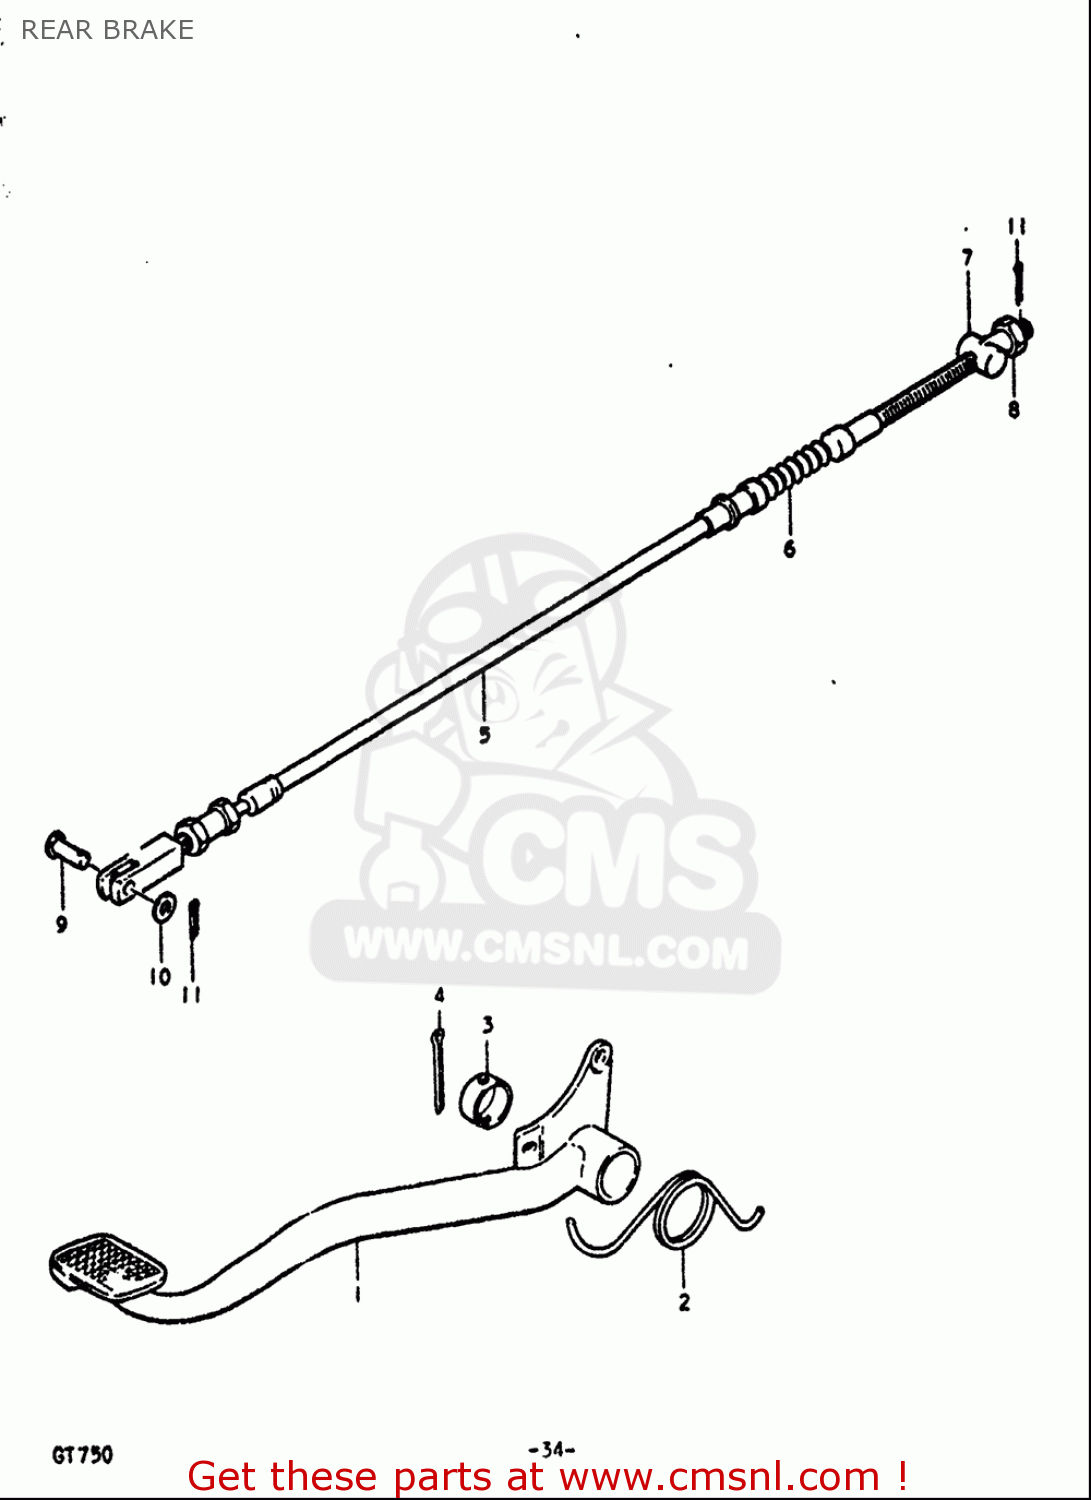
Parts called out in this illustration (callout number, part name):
2	SPRING
4	PIN, COTTER
5	CABLE ASSY,RR BRAKE
6	SEAL,DUST
7	PIN(13X18)
8	NUT
9	PIN(L:17.5)
10	WASHER
11	PIN
